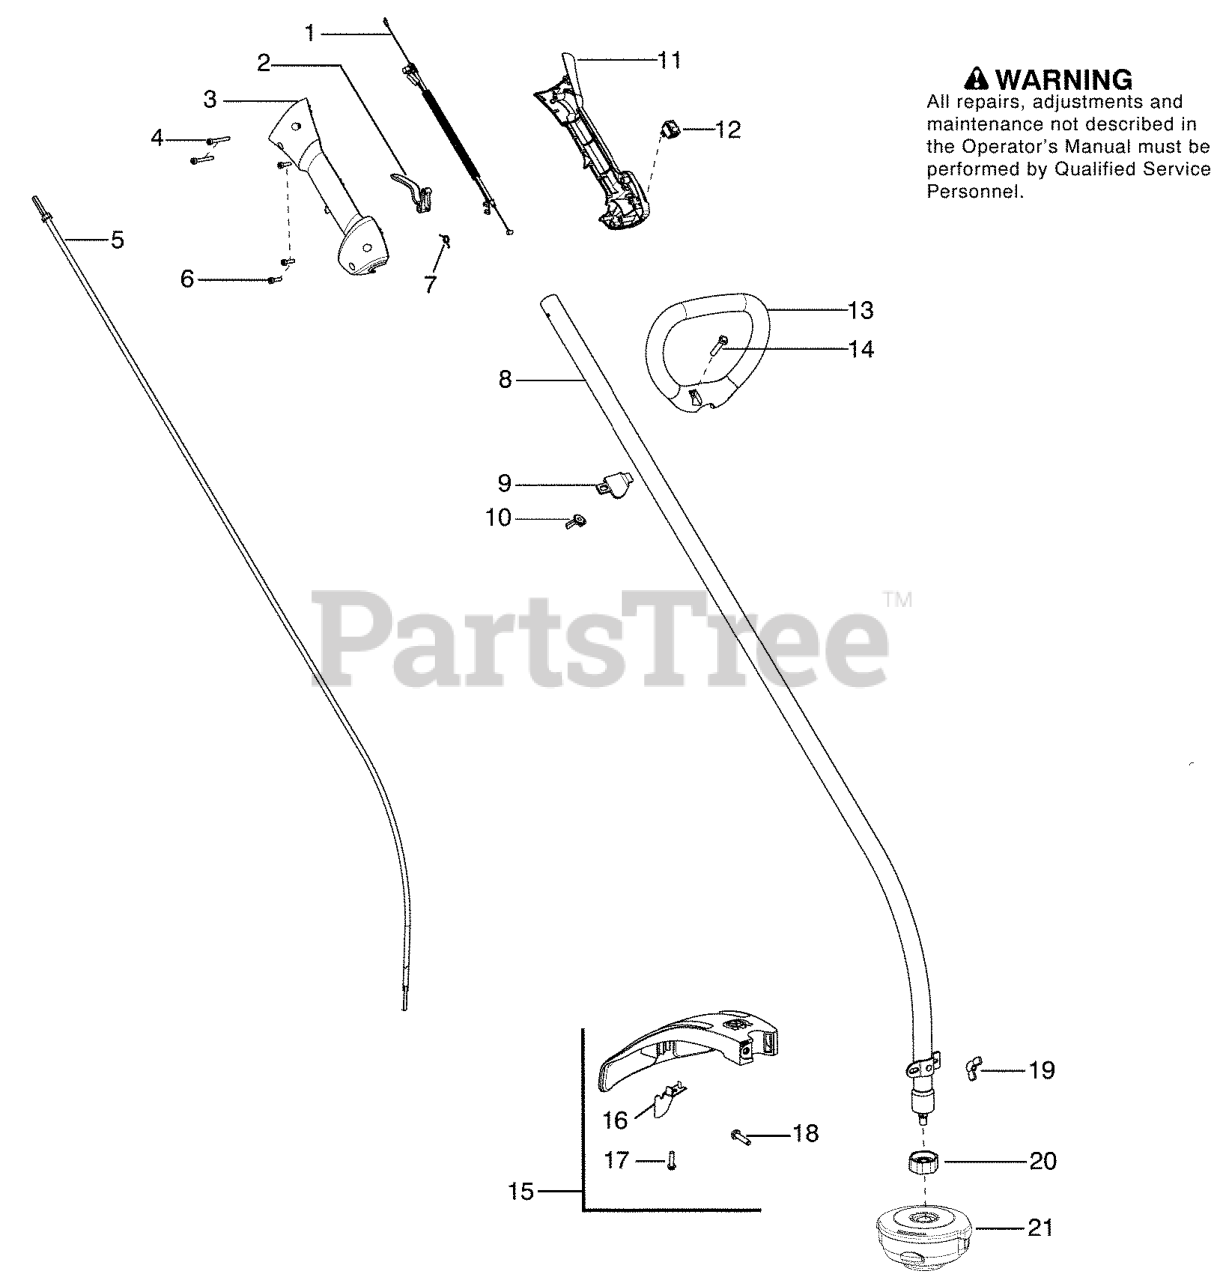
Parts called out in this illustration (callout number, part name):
2	Nut-Carb. Screw
3	Air Box
4	Lever - Choke
5	Kit-Carb. Gasket
6	Adaptor-Carb.
7	Kit-Gasket
9	Cylinder
10	Plug-Spark (RCJ-6Y)
11	Kit-Crankshaft seal
12	Washer-Starter
13	Spring-Starter Cup
14	Assy-Starter Cup
15	Coupling-Starter
16	Assy-Fuel Filter
17	Kit-Fuel Line
18	Assy-Cap w/ret.
19	Kit - Gasket
20	Assy-Fuel Tank
21	Shroud-Rear
24	Handle-Starter
26	Starter Hsg. w/eyelet
27	Kit-Starter Spring
28	Kit-Starter Pulley
30	Assy-Starter Hsg.
31	Isolator-Tank
32	Bolt-Muffler
34	Shield-Heat
36	Guard-Muffler
37	Kit-Spark Arrestor
38	Assy-Muffler
39	Gasket-Paper Metal
41	Module
42	Assy-Leadwire
45	Washer-Clutch
50	Assy-Fan Housing
51	Assy-Clutch Drum
52	Kit-Clutch Assy.
57	Kit-Crankshaft
58	Retainer-Piston Pin
59	Ring-Piston
60	Kit-Piston
61	Kit-Gasket
63	Kit-Carb.
64	Cover-Air Box
66	Kit-Gasket
